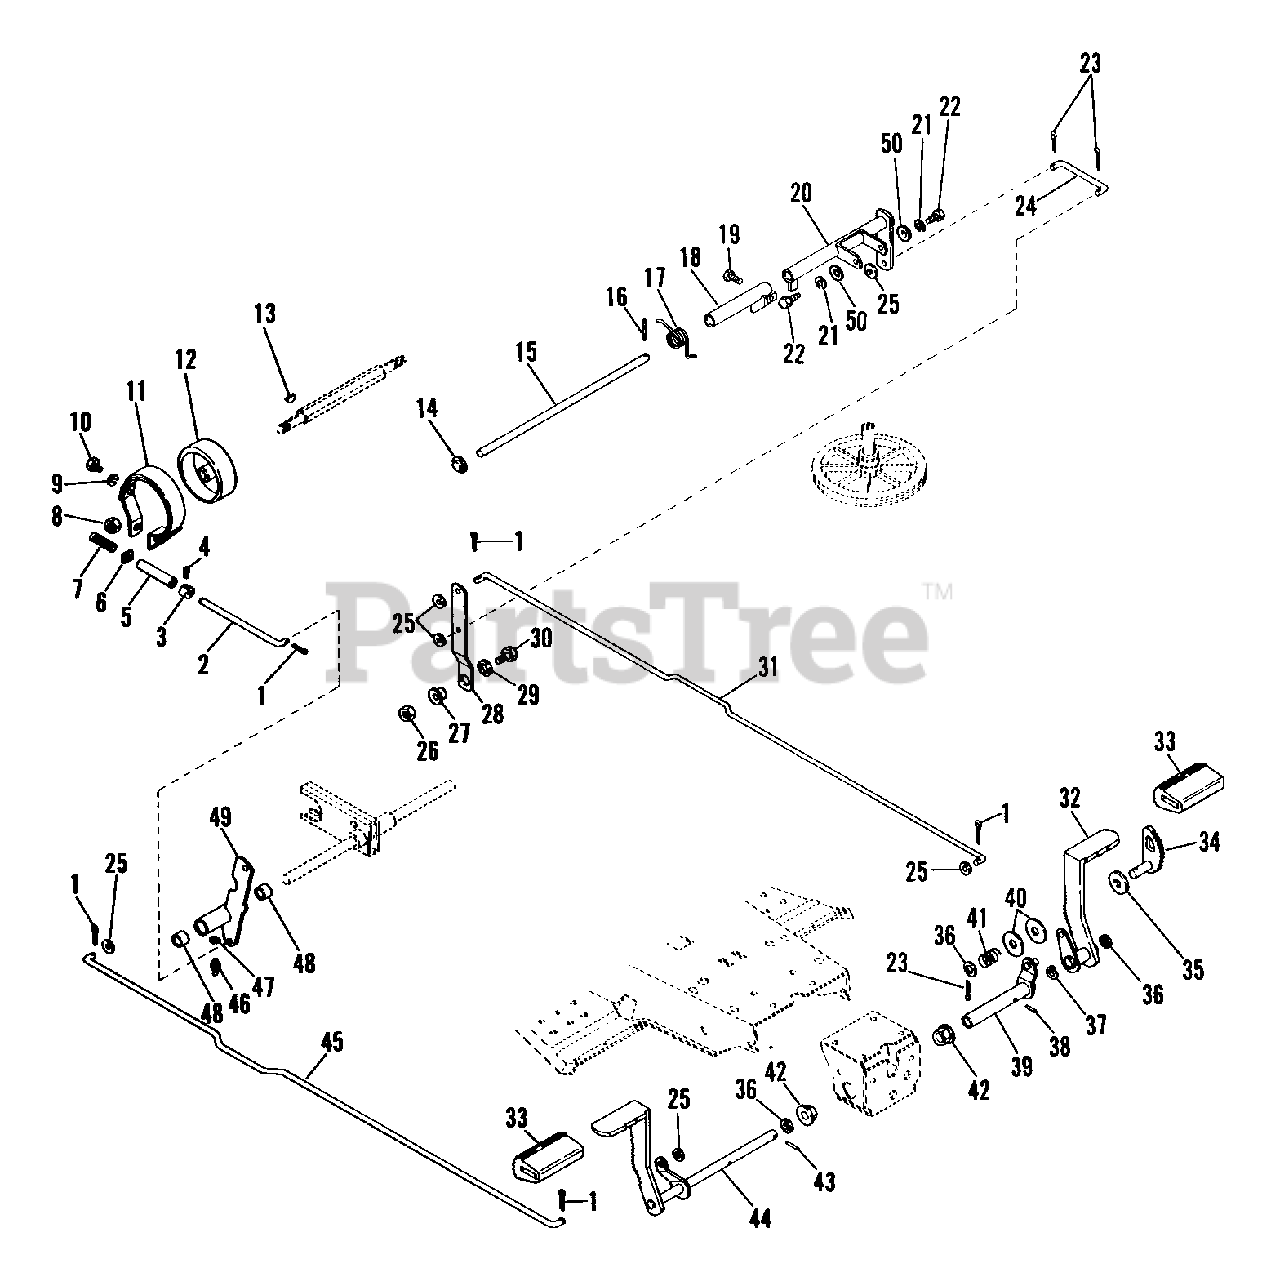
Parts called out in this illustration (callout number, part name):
1	PIN-COTR .09X.75 PL
2	BRAKE ROD
3	SET COLLAR
4	SCR-SET .25-20X.50 SQHCUP HT
5	BRAKE SPACER .5 X .4 X 2.63
6	BRAKE BAND WASHER
7	SG-COMP .102X.85X1.031
8	NUT-LK-CTR .50-20 PL
9	WSHR-LK .312X.097 PL HVY
10	BLT-HEX .31-18X.50 PL GR2
11	BRAKE BAND
12	BRAKE DRUM
13	KEY-WDRF .125X.625X.250 SAE5
14	CAP, .50 ROD YWZC
15	DISC FORK ROD
16	PIN-ROLL .188X1.00
17	SG-TORS .086X.75X1.125
18	NEUTRAL STOP
19	BLT-LK .31-18X.75 GR 5
20	DISK FORK
21	WSHR-LK .375X.115 HVY PL
22	SCREW PIN
23	PIN-COTR .12X1.0 PL
24	CLUTCH LINKAGE ROD
25	WSHR-FL-STL .382X.812X.023 PL
26	NUT-LK-CTR .375-16 GR A PL
27	SHOULDER SPACER
28	CLUTCH LINK BAR
29	WSHR-FL-STL .630X1.005X.062 PL
30	BLT-HEX .38-16X.75 PL GR2
31	CLUTCH ROD
32	CLUTCH BRAKE LEVER
33	PEDAL COVER
34	BRAKE LATCH
35	WSHR-FL-STL .511X1.441X.125 PL
36	WSHR-FL-STL .505X.875X.024 PL
37	WAVE WASHER .531X.781X.125FH
38	PIN-ROLL .188X.88
39	CLUTCH BRAKE LEVER
40	WSHR-FL-STL .531X.938X.104 PL
41	SG-COMP .072X.687X.75
42	FLANGE BUSHING
43	PIN-ROLL .125X1.00
44	BRAKE LEVER
45	BRAKE ROD
46	SPIN DRIVE ZERK FITTING
47	WSHR-LK .250X.047 LT PL
48	BSHG-SLV .625X.750X.500 BR
49	CLUTCH BRAKE BELL CRANK
50	WSHR-FL-STL .38X.875X.083 PL
